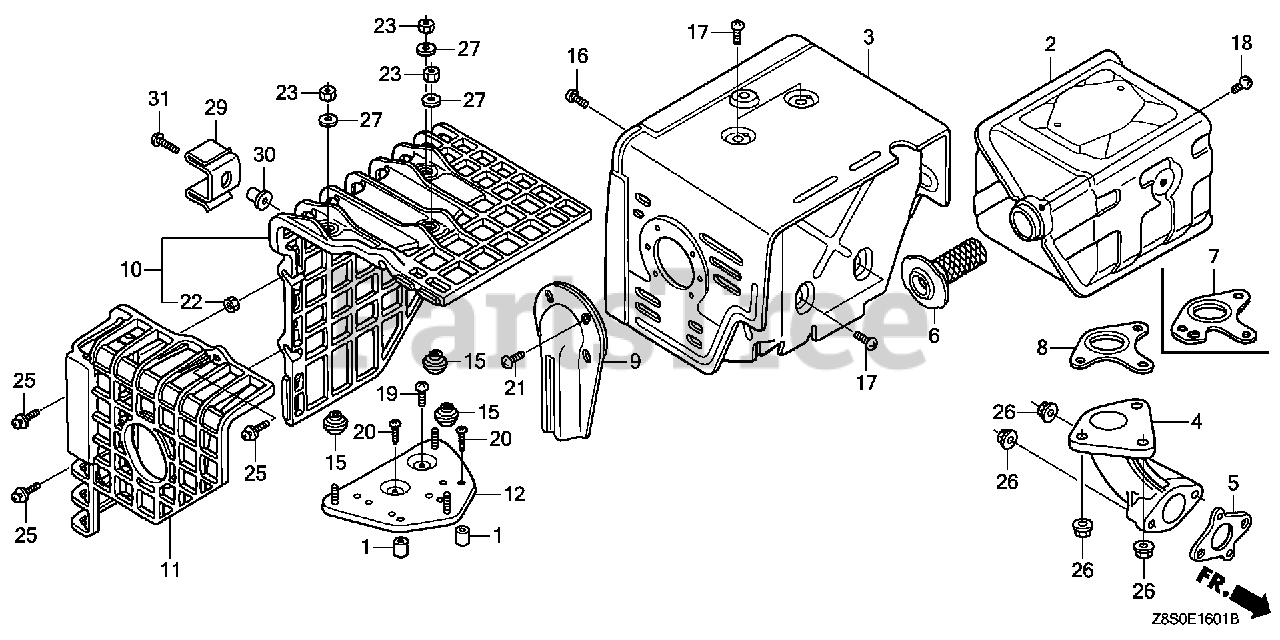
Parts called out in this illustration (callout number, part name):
2	MUFFLER (100DB)
3	PROTECTOR, MUFFLER
5	GASKET, EX. PIPE
6	ARRESTER, SPARK
7	GASKET, MUFFLER (ARRESTER) (NIPPON LEAKLESS)
7	GASKET, MUFFLER (ARRESTER)(THAI LEAKLESS)
8	GASKET, MUFFLER (NIPPON LEAKLESS)
8	GASKET, MUFFLER (THAI LEAKLESS)
16	SCREW, TAPPING (6X10)
17	SCREW, TAPPING (5X8)
18	SCREW, TAPPING (4X6)
26	NUT, FLANGE (8MM)
